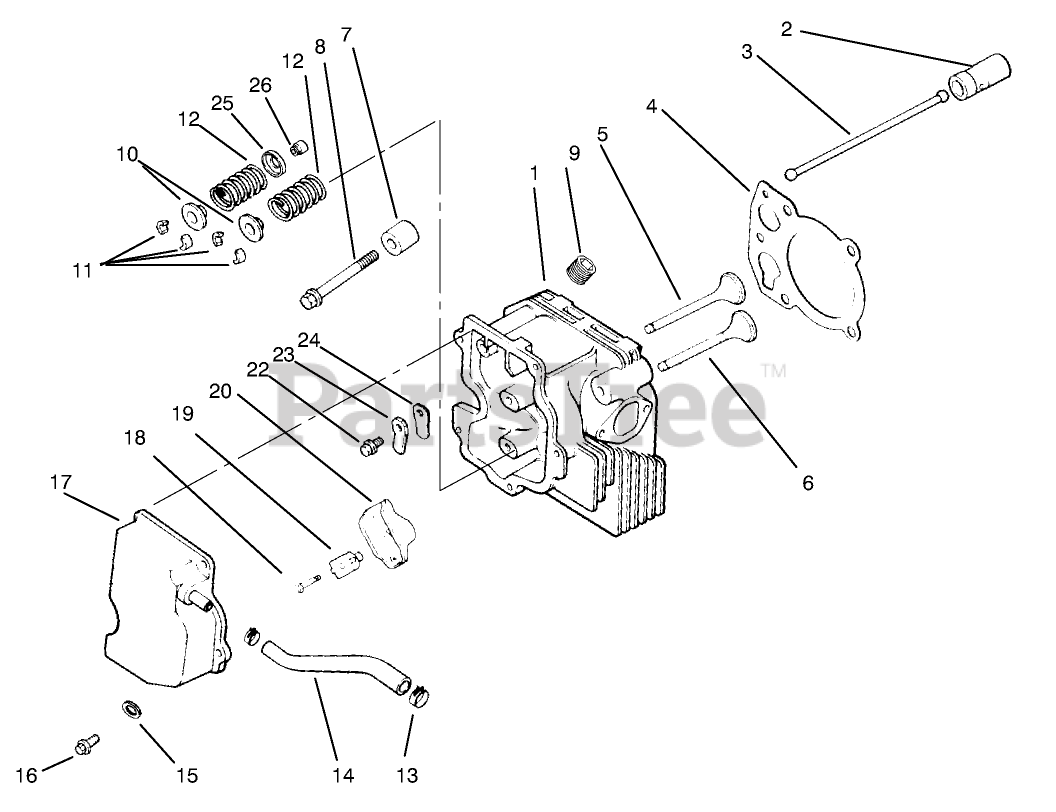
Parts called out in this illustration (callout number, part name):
1	Cylinder Head
2	Lifter-Valve
3	Rod-Push (Only On: 72042,72043,72062,72063)
4	Gasket-Cylinder Head
5	Valve-Intake STD (Only On: 72042, 72063, 72062, 72043)
5	Valve-Intake .25 (Only On: 72042,72043,72062,72063)
6	Valve-Exhaust STD (Only On: 72042,72043,72062,72063)
6	Valve-Exhaust .25 (Only On: 72042, 72063, 72062, 72043)
7	Spacer-Head Bolt Exhaust (Only On: 72042, 72063, 72062, 72043)
8	Screw M10x1.5x80 (Only On: 72042, 72063, 72062, 72043)
10	Cap-Valve Spring
11	Kit-Retainer
12	Spring-Valve Intake (Only On: 72042, 72063, 72062, 72043)
13	Clamp
14	Hose-Breather (Only On: 72042, 72063, 72062, 72043)
15	Washer-Flat (Only On: 72042, 72063, 72062, 72043)
17	Cover-Valve W/Nipple (Only On: 72042, 72063, 72062, 72043)
19	Pivot-Rocker Arm
20	Arm-Rocker
23	Retainer-Reed
24	Reed-Breather
25	Retainer-Spring
26	Seal-Valve Stem
